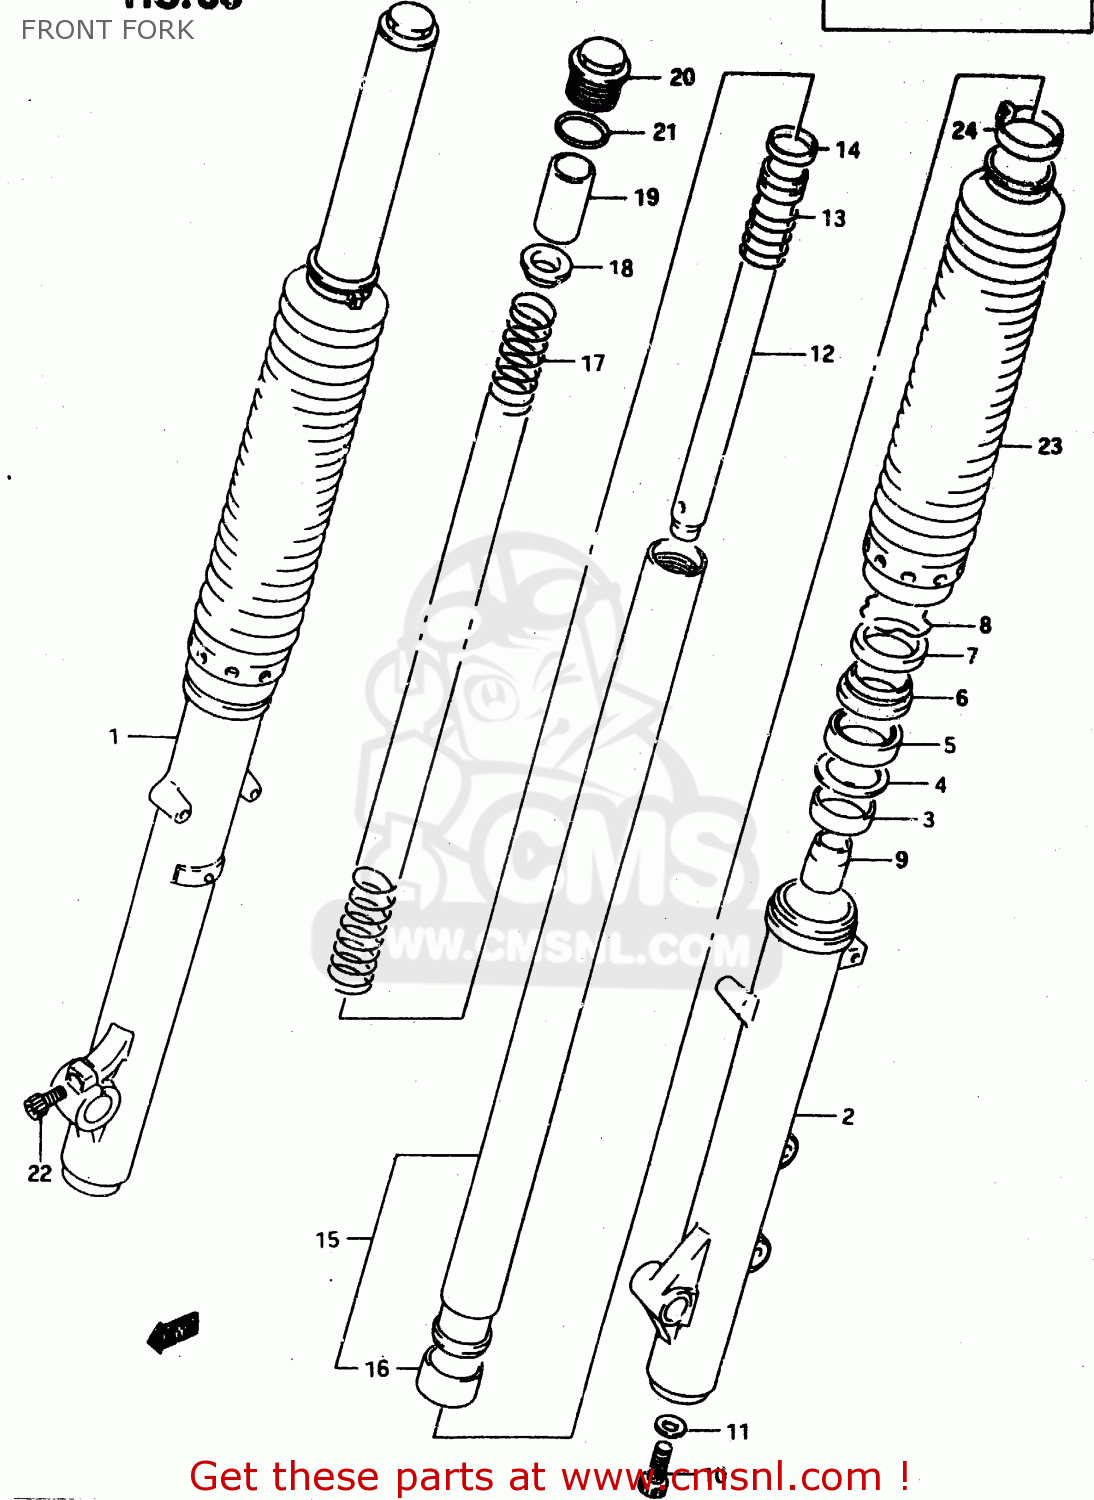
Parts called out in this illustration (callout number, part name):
1	TUBE,OUTER,R
2	TUBE,OUTER,L
3	METAL,SLIDE
4	WASHER,FORK OIL SEAL
5	SEAL,OIL
6	SEAL,DUST
7	WASHER
8	RING,OIL SEAL STOPPER
9	PIECE,OIL LOCK
10	BOLT(14X25)
11	GASKET (NAS)
12	CYLINDER
13	SPRING,REBOUND
14	RING,FR FORK PISTON
15	TUBE,INNER
16	PISTON
17	SPRING,MAIN
18	GUIDE,SPRING
19	SPACER,SPRING
20	CAP,FORK
21	O RING(D:3.5,ID:31.7)
22	BOLT,SOCKET HEAD(8X22)
23	BOOT
24	BAND,BOOT
